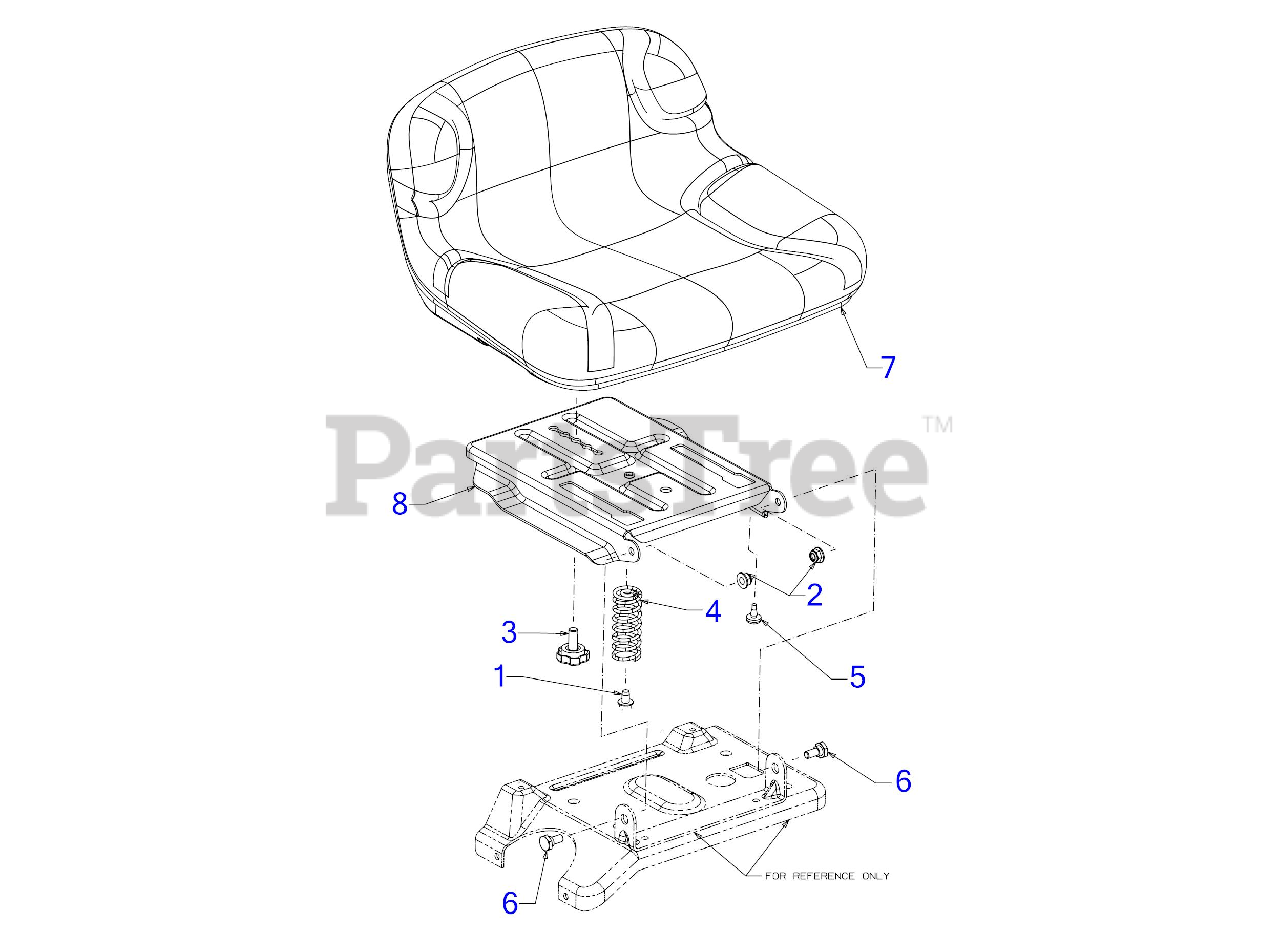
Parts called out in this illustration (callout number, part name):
1	SCREW 5/16-18 x .500
2	FLANGE LOCK NUT 5/16-18
3	SEAT ADJUSTMENT KNOB
4	SEAT SPRING
5	RUBBER BUMPER
6	SHOULDER SCREW .437
7	LOW BACK SEAT (BLACK NO OPS)
8	MANUAL SEAT ADJUSTMENT BRACKET
